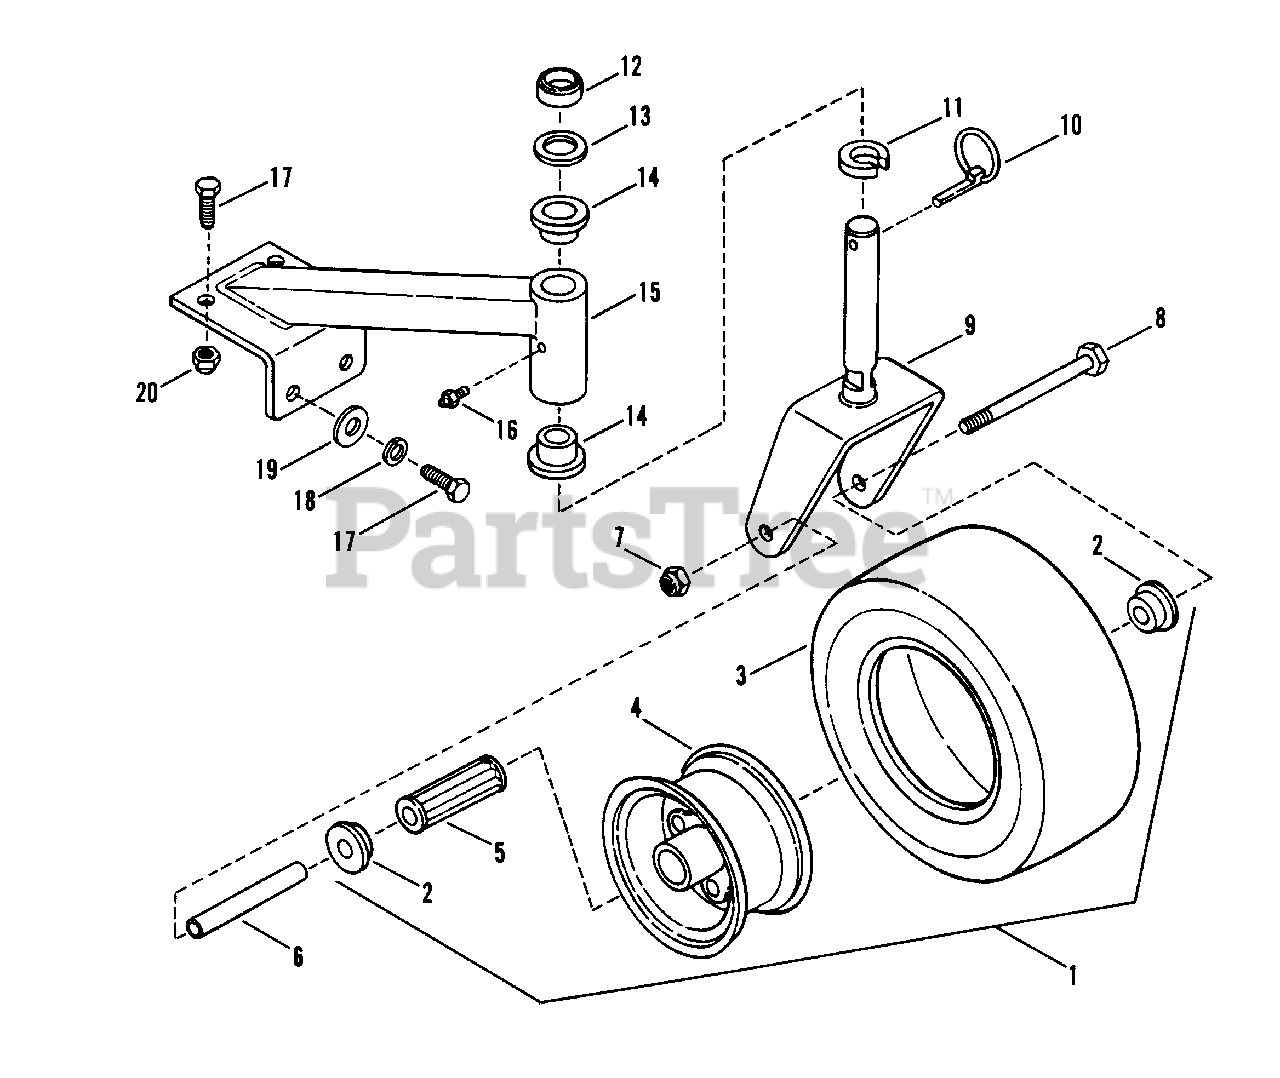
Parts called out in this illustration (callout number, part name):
1	ASSEMBLY, Wheel & Tire
2	RETAINER, Flanged
3	TIRE, 9 x 3.50-4
4	ASSEMBLY, Wheel
5	ROLLER BEARING
6	SLEEVE, Axle
7	NUT, 1/2-13 HEX NYLON LOCK
8	BOLT, 1/2-13 X 5-1/2" GD5 YZ
9	YOKE, Caster Weldment
10	PIN, Lynch
11	SPACER
12	SPACER, 1" x 1 3/8 x .30" (PM)
13	SPACER
14	BUSHING, Caster
15	ASSEMBLY, Caster Support
16	FITTING, Lube
17	BOLT, 3/8-16 X 1" GD5 CZ
18	WASHER, 3/8 Split Lock
19	WASHER, 3/8" USS
20	NUT, 3/8-16 HEX NYLON LOCK
